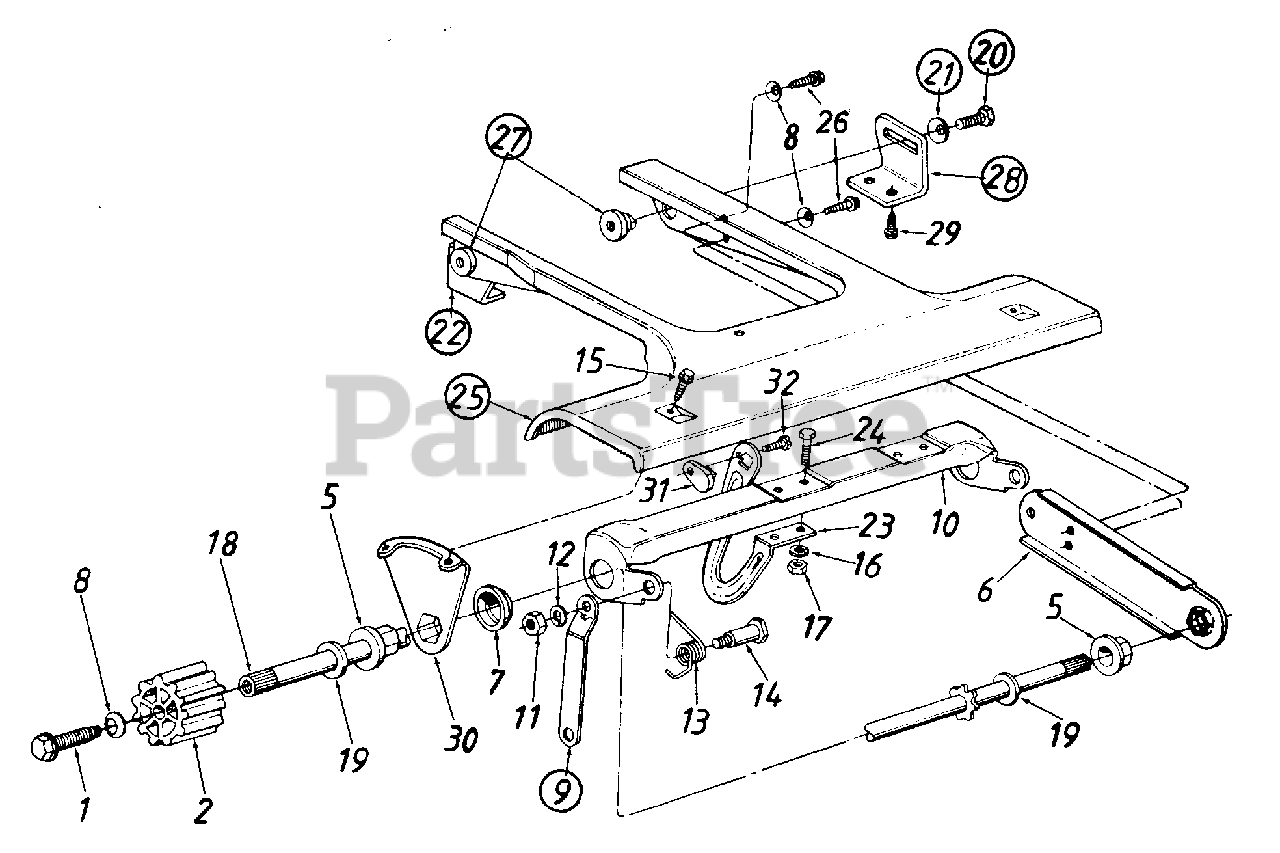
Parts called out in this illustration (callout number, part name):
1	Hex Wash. Hd. Tap Scr. 1/4-20 x .75" Lg.
2	Wheel Drive Pinion-Half
5	Hex Flange Brg. .504" I.D.
8	Bell-Wash. .265" I.D. x .75" O.D.
9	Link
10	Drive Engagement Cam
11	Hex Nut 5/16-18 Thd.
12	L-Wash. 5/16" I.D.
13	Torsion Spring-R.H.
14	Shoulder Bolt .437" Dia.
15	Hex L-Hd. AB-Tap Scr. 1/4" x .62" Lg.
16	L-Wash. 1/4" I.D.
17	Hex Nut 1/4-20 Thd.
18	Drive Shaft Ass'y.
19	Fl-Wash. .531" I.D. x .93" O.D.
20	Hex Bolt 5/16-18 x 5/8" Lg.
21	Bell-Wash. .345" I.D. x .88" O.D.
22	Pivot Bracket - R.H.
25	Front Pinion Pivot Cover
27	Shoulder Nut
28	Pivot Bracket - L.H.
29	Hex Wash. Hd. AB-Tap Scr. 1/4 x.62" Lg.
32	Hex B-Tap Scr. #10 x .44" Lg.
